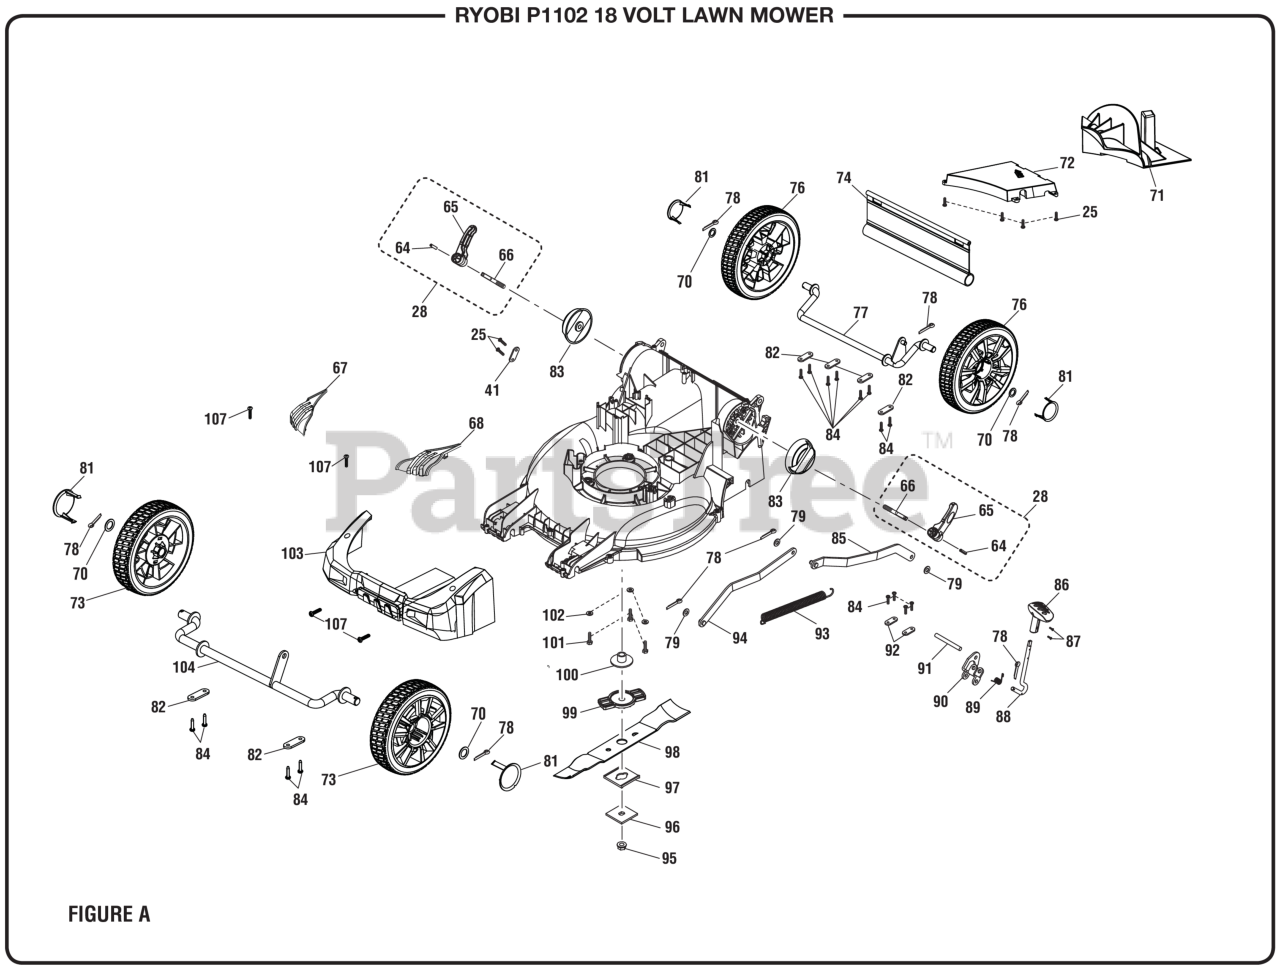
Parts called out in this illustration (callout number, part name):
25	Screw (M4 x 16 mm, T20 Torx Pan Hd.).
28	Handle Lock Assembly
41	Wire Press Plate
64	Spring Pin
65	Adjust Height Handle
66	Quick Lock Press
67	Grass Protector (Right)
68	Grass Protector (Left)
70	Washer (ID13.5 x OD20 x 1t)
71	Mulching Plug
72	Rear Cover
73	Front Wheel w/Bearing & Cap 6 in.
74	Rear Skirt
76	Rear Wheel w/Bearing & Cap 8 in.
77	Rear Wheel Axle
78	Cotter PinÏ? (2.5)
79	Washer (ID8.4 x OD18 x 1t)
81	Wheel Cover
82	Axle Pressure Plate
83	Quick Lock Press Block
84	Screw (M4 x 18 mm, T20 Torx Pan Hd.)
85	Rear Lift Rod
86	Height Adjustment Handle
87	Screw (M3 x 9 mm, Flat Hd.)
88	Height Adjustment Lever
89	Torsion Spring (Height Adjustment)
90	Adjustment Height Bracket
91	Axle (Height Adjustment)
92	Pressure Plate (Height Adjustment)
93	Rentention Spring
94	Front Lift Rod
95	Blade Nut (M10 x 1.25, Hex Flange Hd.)
96	Metal Blade Retainer
98	Blade (16 in.)
99	Blade Holder
100	Motor Shaft Bushing
101	Bolt (M6 x 26 mm, Hex Hd.)
102	Washer (ID6.2 x OD15 x 0.08t)
104	Front Wheel Axle
107	Screw (M4 x 20 mm, T20 Torx Pan Hd. S.T.)
